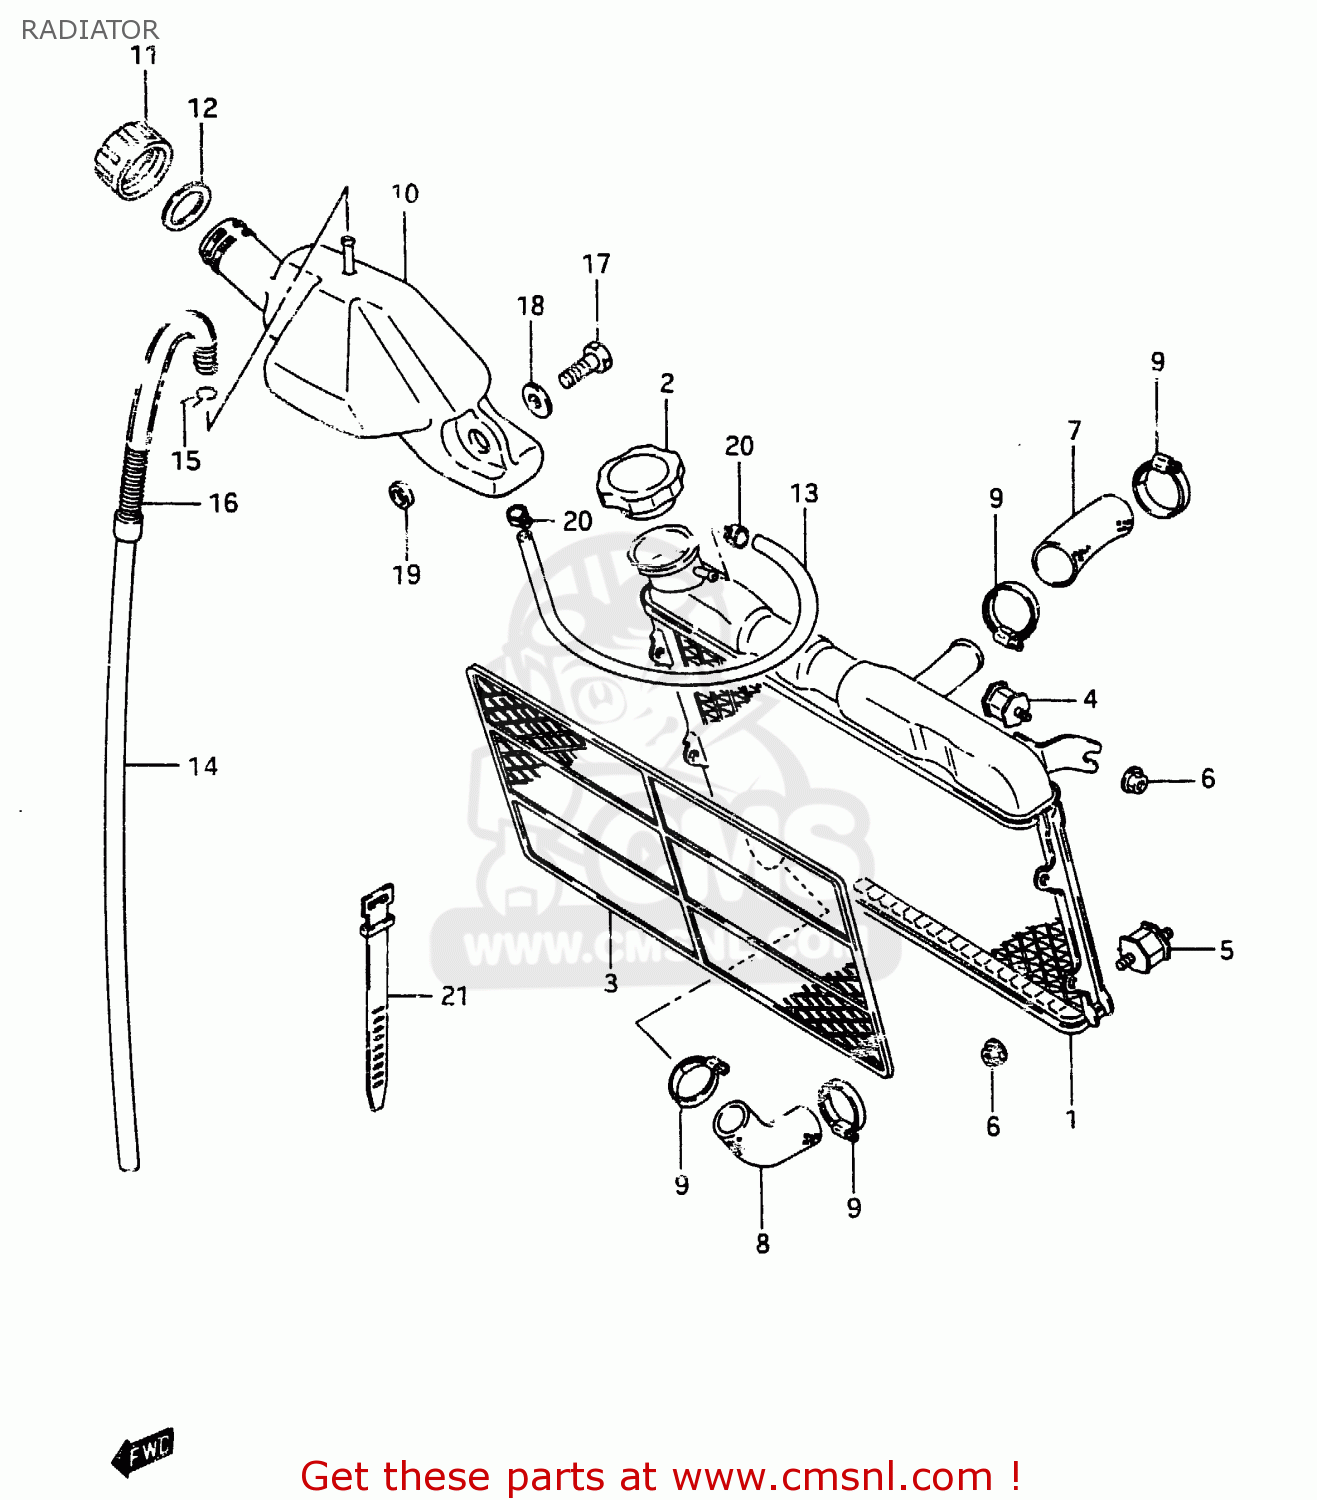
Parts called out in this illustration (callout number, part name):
1	RADIATOR
2	CAP,RADIATOR
3	NET,RADIATOR
4	BOLT,RADIATOR CUSHION
5	BOLT, RADIATOR CUSHION NO.2
6	NUT 6MM
7	HOSE,RADIATOR INLET
8	HOSE, RADIATOR OUTLET
9	CLAMP
10	TANK ASSY, RESERVOIR
11	CAP,RESERVOIR TANK
12	GASKET,RESERVOIR TANK CAP (NAS)
13	HOSE, INLET
14	HOSE, OUTLET
15	CLIP
16	SPRING
17	BOLT (8X16)
18	WASHER (8.2X20X1.6)
19	SPACER(8.2X14X4.5)
20	CLIP
21	CLAMP(L:125)
